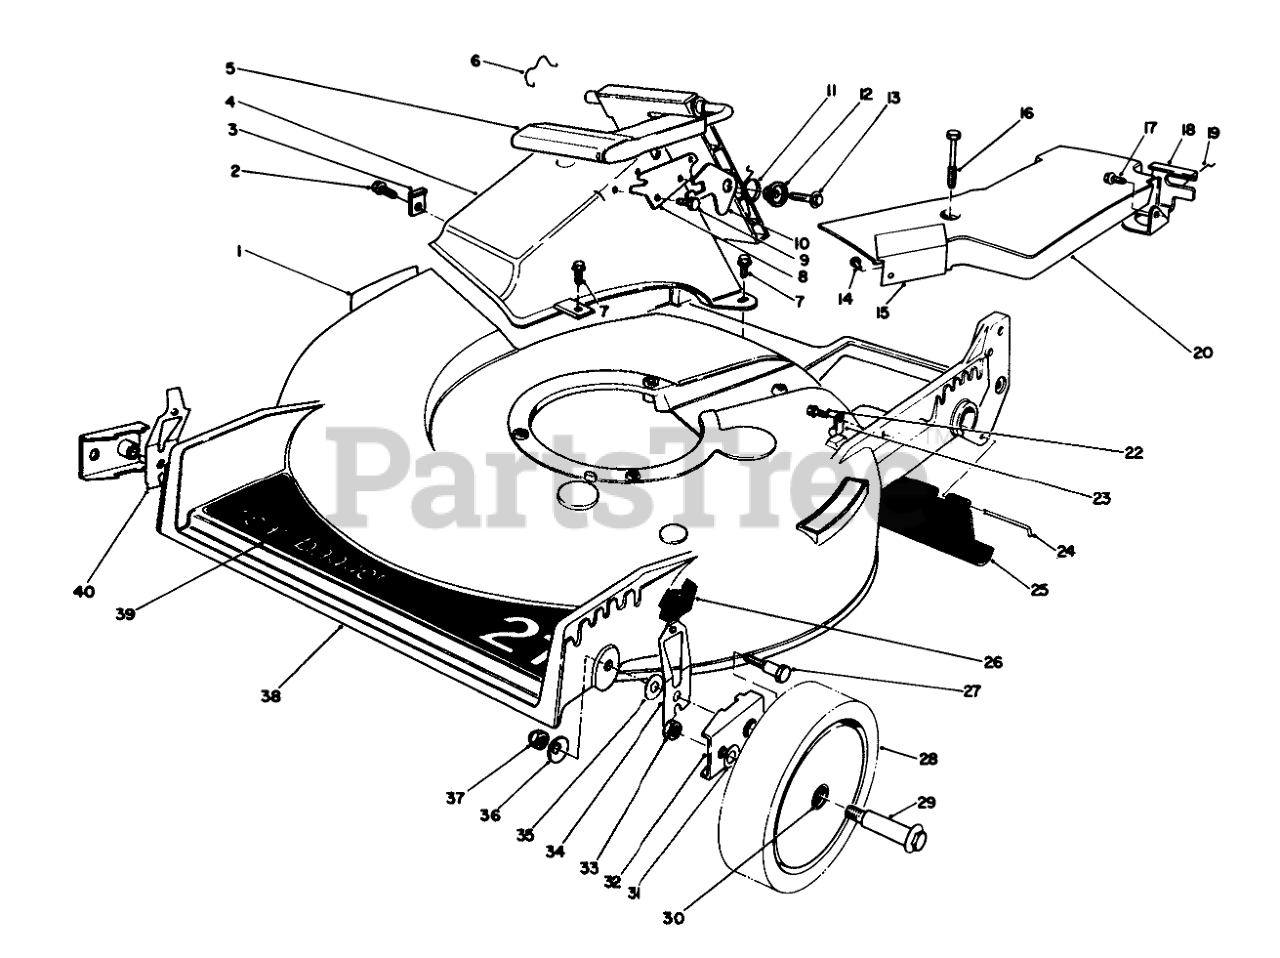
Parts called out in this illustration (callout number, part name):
1	DECAL-DANGER
2	SCREW
3	TUNNEL CLIP
4	Tunnel-Discharge (Incl. Ref. #1)
5	Discharge Door Assembly
6	DOOR RET SPRING
7	SCREW-HWH
8	DOOR LATCH PLATE
9	SCREW-PLASTITE
10	SAFETY LATCH
11	TORSION SPRING
12	DOOR SPACER
13	SCREW-HWH
14	RIVET-HEAD, FLAT
15	HEAT SHIELD
16	SCREW-HHFTF
17	SCREW-HWHTF
18	Bracket-Traction Adj.
19	RETAINER-CABLE
20	Belt Cover Assembly (Incl. Ref. #14 & 15)
22	SCREW
23	CLAMP-CABLE
24	ROD-SHIELD
25	SHIELD-TRAILING
26	KNOB-ARM
27	PIVOT SCREW
28	Wheel & Tire Assembly (Incl. Ref. #30)
29	BOLT-WHEEL
30	BUSHING
31	WASHER
32	HP PIVOT ARM ASM
33	Nut
34	L. HP SPRING ARM ASM
35	WASHER-PIVOT
36	WASHER-BELLEVILLE
37	NUT-LOCK, NI
38	Housing (Incl. Ref. #1)
39	DECK DECAL
40	R HP SPRING ARM ASM
